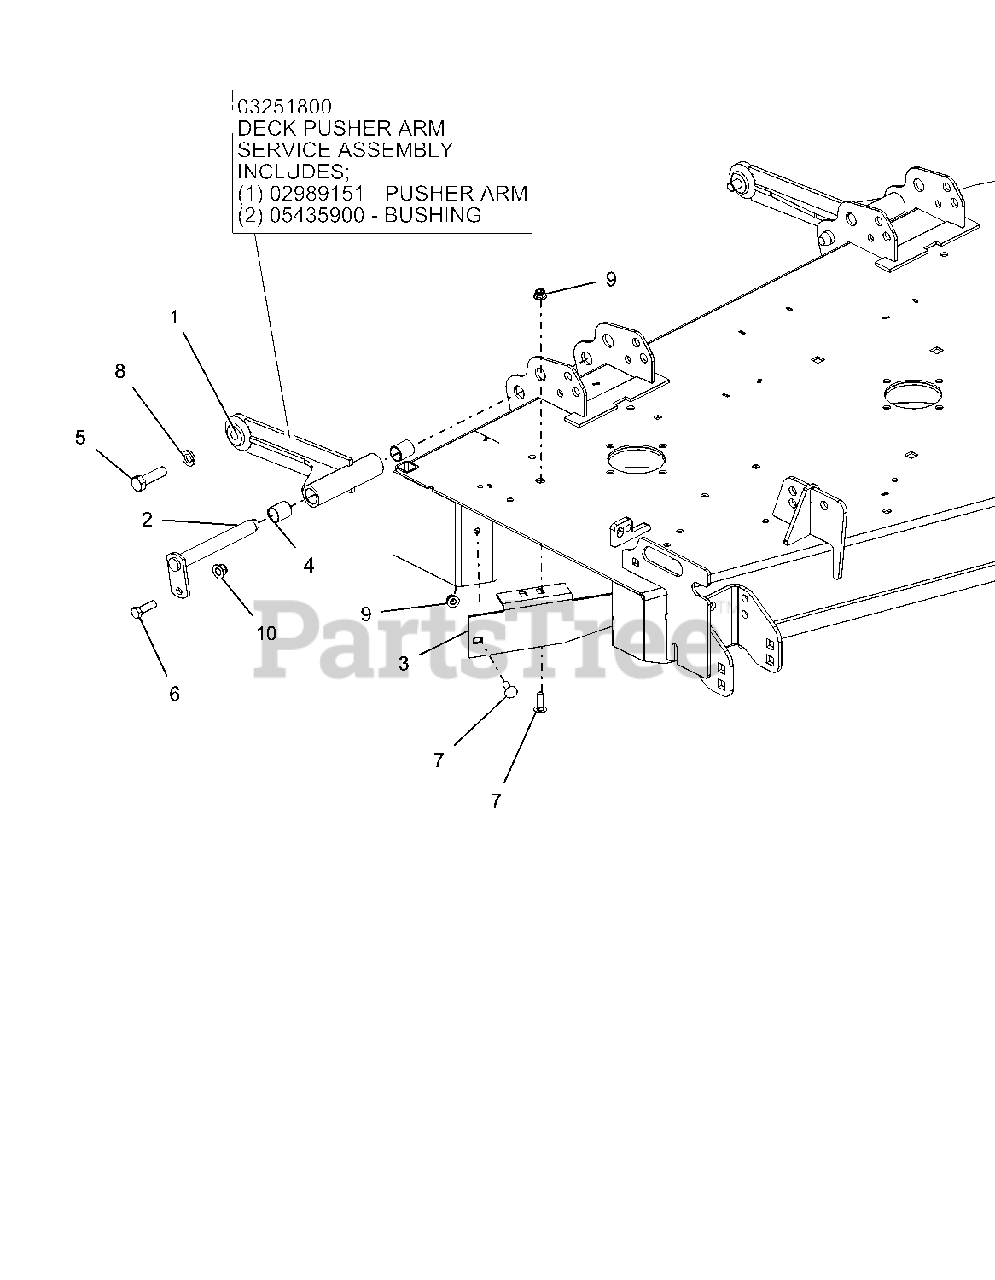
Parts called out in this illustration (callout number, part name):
1	DECK PUSHER ARM WLDMT - BLK
1	DECK PUSHER ARM SERVICE ASSEMBLY
1	PUSHER ARM
1	BUSHING
2	WLDMT, MOWER MTG. PIN
3	BAFFLE, DISCHARGE, 44"-48"-RED
4	BRG, .750 X .875 X 1.000
5	BLT-HEX .50-13X1.75 G5 YZ EP80
6	BLT-HEX .38-16X1.25 GR5 YWZC
7	BLT-RDHDSQSHNK .31-18X1.00 G5 Y
8	WSHR-LK .50X.125 REG YWZC
9	NUT-LK-NYL-FLG .31-18 YWZC
10	NUT-LK-NYL-FLG .38-16 YWZC
